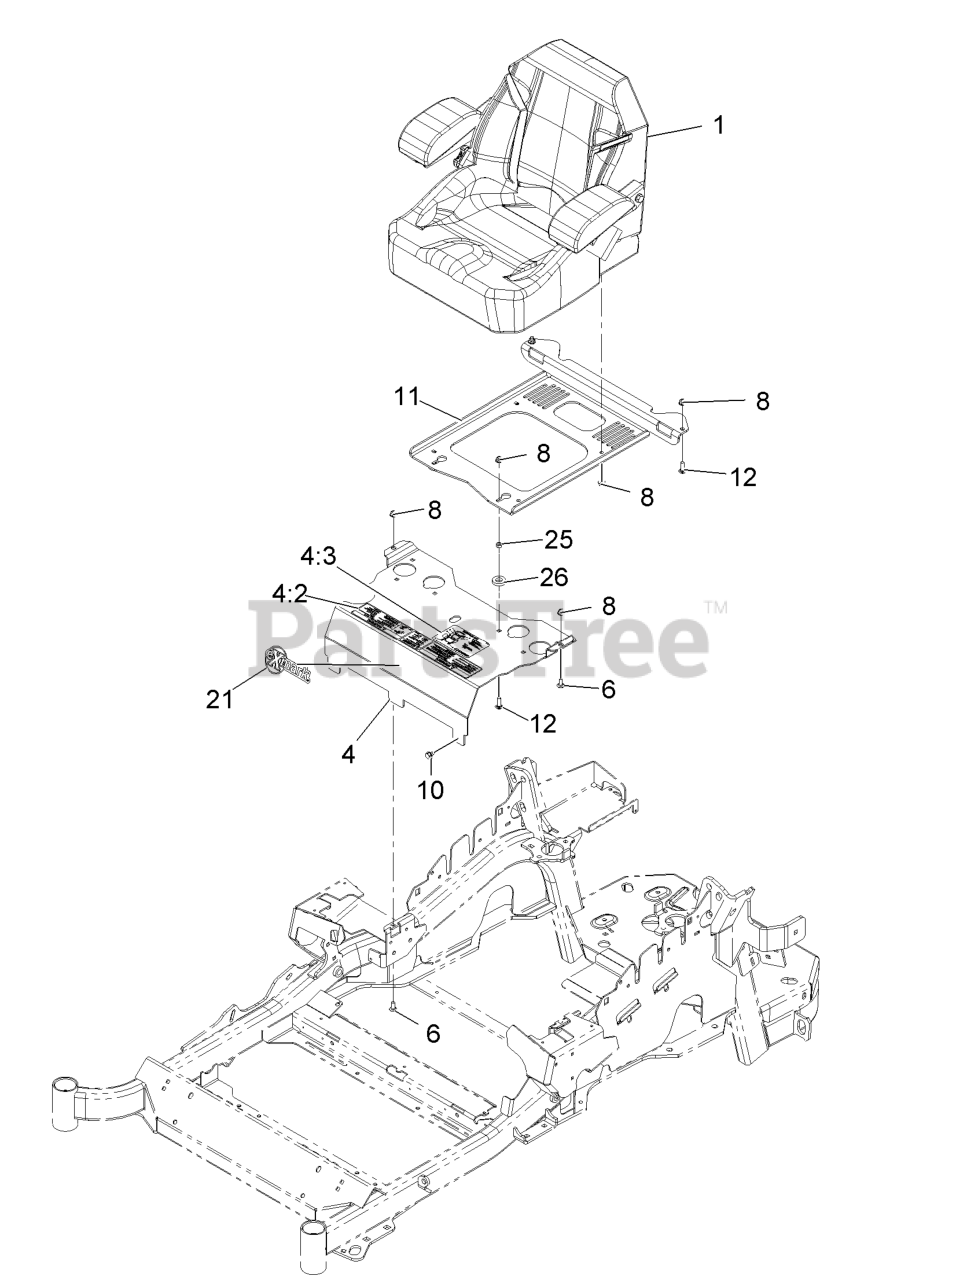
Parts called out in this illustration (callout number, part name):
4	MOUNT-SEAT
4:2	DECAL-CONSOLE
4:3	DECAL-SERVICE AID
6	SCREW-CARR
8	NUT-HF, NI
11	PLATE-SUPPORT, SEAT
12	SCREW-CARR
25	NUT-HEX
